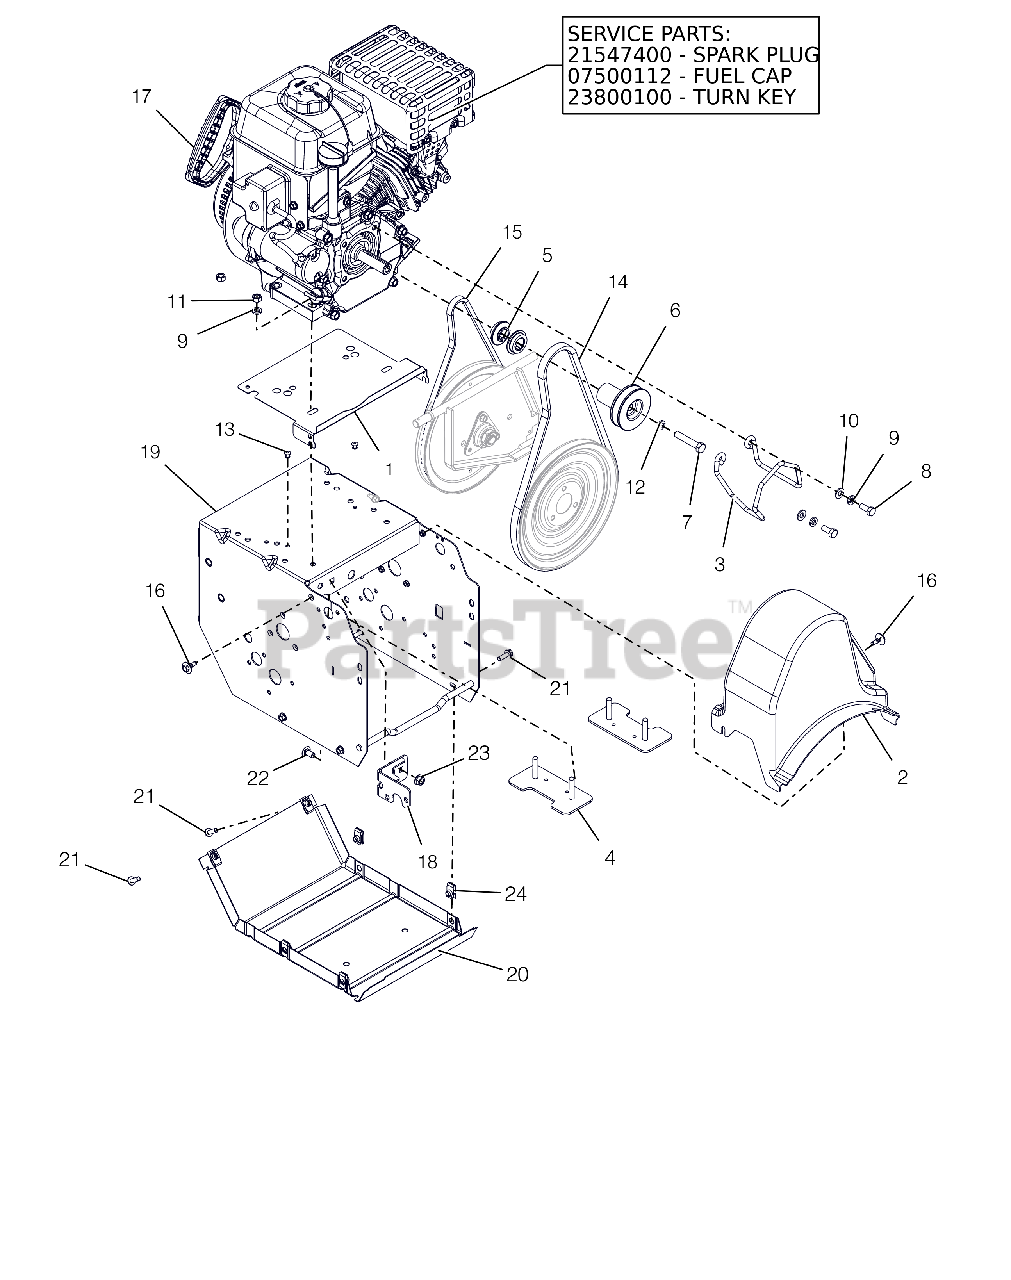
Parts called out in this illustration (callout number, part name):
1	BAFFLE, COMPACT
2	COVER, COMPACT BELT
3	FINGER, BELT
4	STRAP, ENGINE BOLT-WELDMENT
5	TRACTION SHEAVE HALF
6	SHEAVE, AUGER 3/4 - PM
7	BLT-HEX .38-24X2.0 YWZC
8	BLT-HEX .31-24X.75 YWZC GR5
9	WSHR-LK .312X.097 HVY YWZC
10	@WSHR-FL-STL.344X.688X.065YWZC
11	@NUT-HEX .31-18 YWZC
12	WSHR-LK .312X.097 HVY YWZC
13	RVT-POP .187 YZ
14	V-BELT, HA-RAW EDGE
15	V-BELT, 3L-WRAPPED
16	SCR-TAP .25-20X.5 CAPTIVE
17	ENGINE, ARIENS AX208 120V/60W
17	ENGINE, ARIENS AX208 240V/60W
17	ENGINE, AX208 GEN 2 120V
17	PLUG, SPARK
17	CAP, FUEL TANK BLACK
17	KEY, TURN LCT (2/PACKAGE)
18	WELDMENT, FRAME BRACKET
19	FRAME, MAIN
20	COVER, BOTTOM
21	BLT-HEX .25-20X.75 HWH YZ GR5
22	@BLT-RHDSSQNK .31-18X.62 G5YZ
23	@NUT-LK-TOP-FLG .31-18 YWZC
24	NUT-RTNR .25-20X.56
